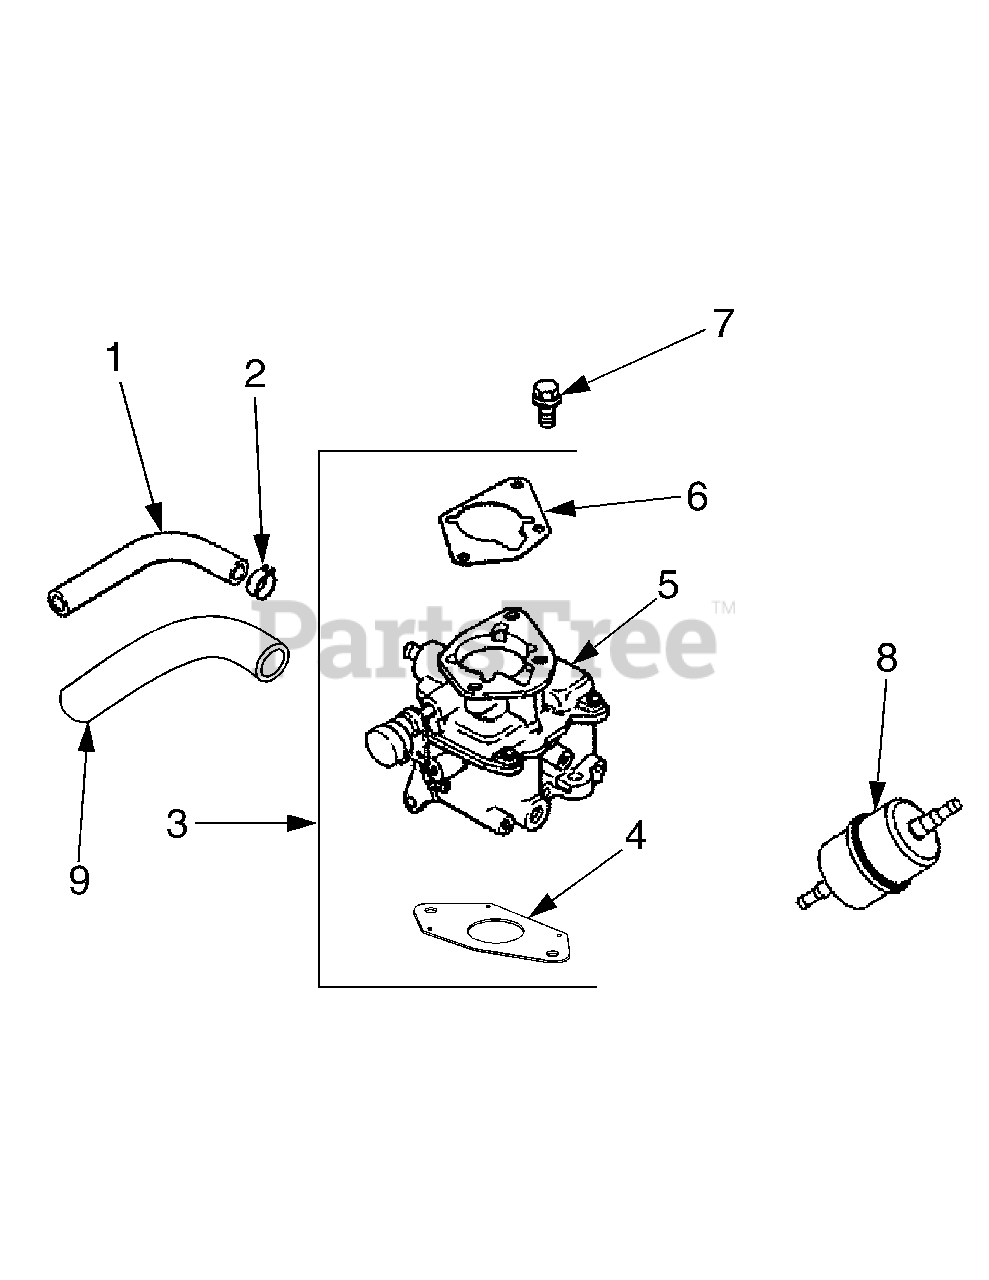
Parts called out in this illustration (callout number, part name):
1	Line, Fuel 15.5"
2	Clamp, Hose
3	Kit, Carburetor w/Gasket (Includes 4-6)
4	Gasket, Carburetor / Carburetor Assembly (not avail separately)
6	Gasket, Air Cleaner Base
7	Screw, Hex Flange, M6 x 1.0 x 25
8	Filter, Fuel
9	Sleeve, Insulator
